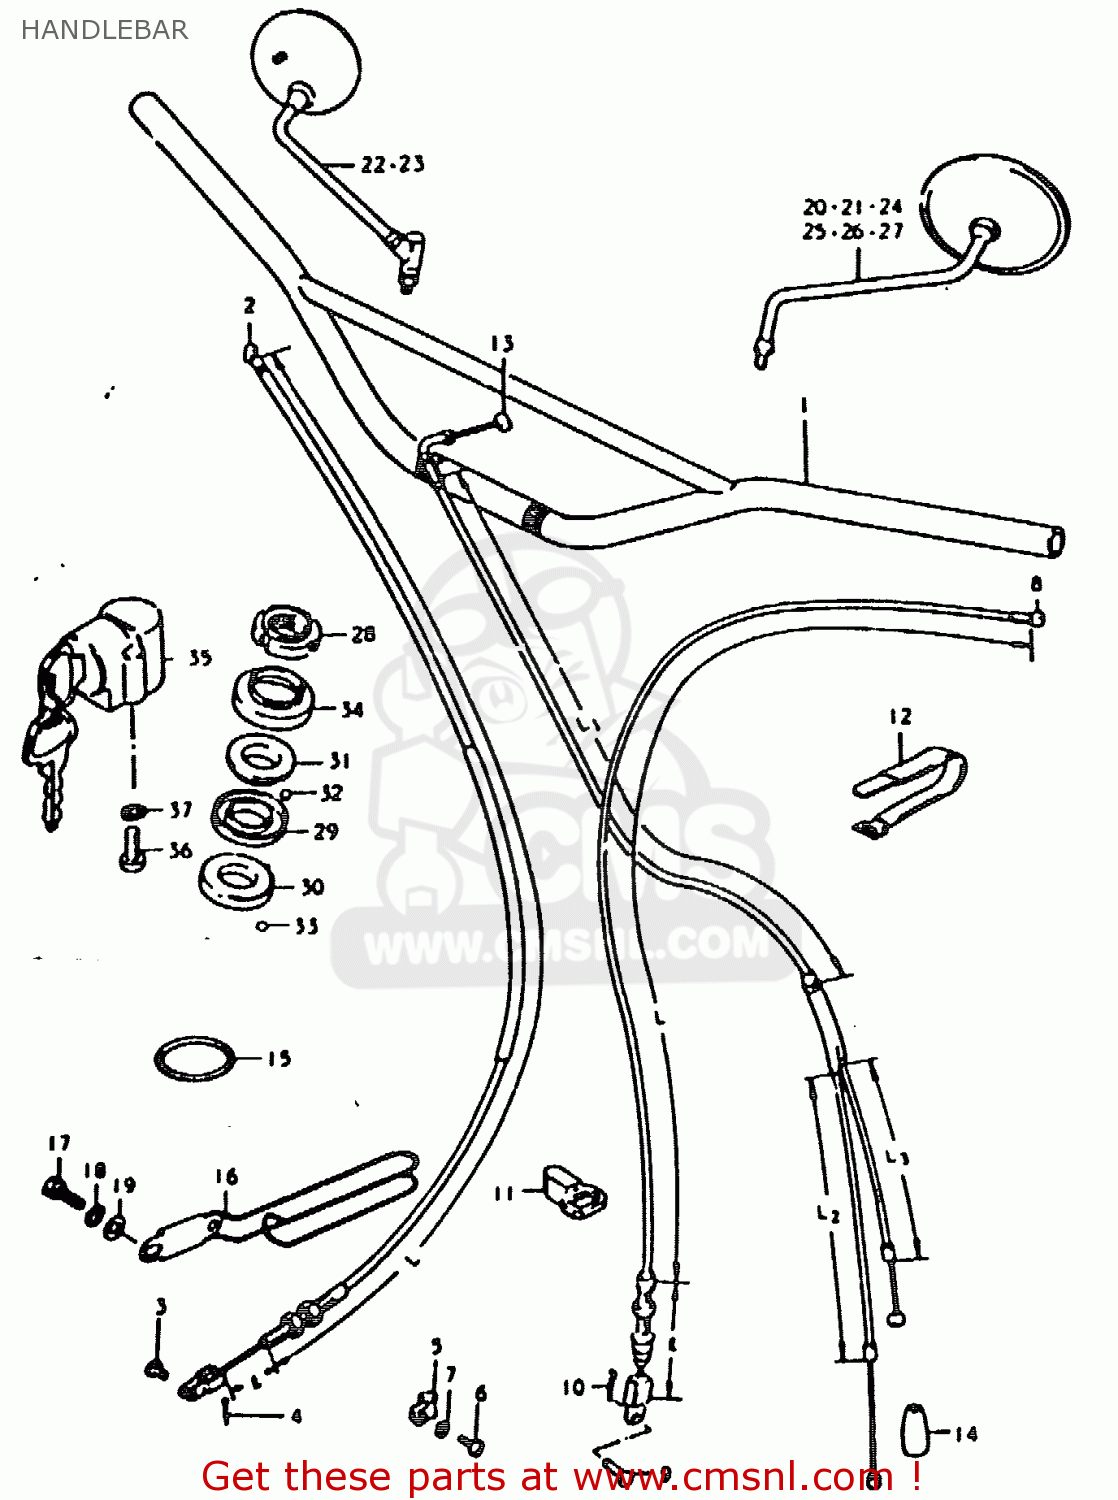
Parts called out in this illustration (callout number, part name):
1	HANDLEBAR
2	CABLE,FRONT BRAKE
3	PIN(L:13.5)
4	PIN
5	GUIDE,CABLE
6	SCREW
7	LOCK WASHER
8	CABLE ASSEMBLY,CLUTCH
9	PIN(L:15)
10	PIN
11	GUIDE,CLUTCH CABLE
12	CLAMP
13	CABLE ASSEMBLY,THROTTLE
14	SEAL,DUST(7X18X30)
15	O RING,RR BRAKE CABLE
16	GUIDE,CABLE
17	BOLT 8X12
18	LOCK WASHER
19	WASHER
22	MIRROR ASSY,RH
28	NUT,STEERING STEM(25X44X10)
29	RACE,STEERING INNER UPR
30	LACE,STEERING INNER LWR
31	RACE,STEERING OUTER UPR
32	BALL
33	BALL
34	DUST SEAL,STEERING UPR
35	LOCK ASSEMBLY,STEERING
36	SCREW
37	LOCK WASHER
